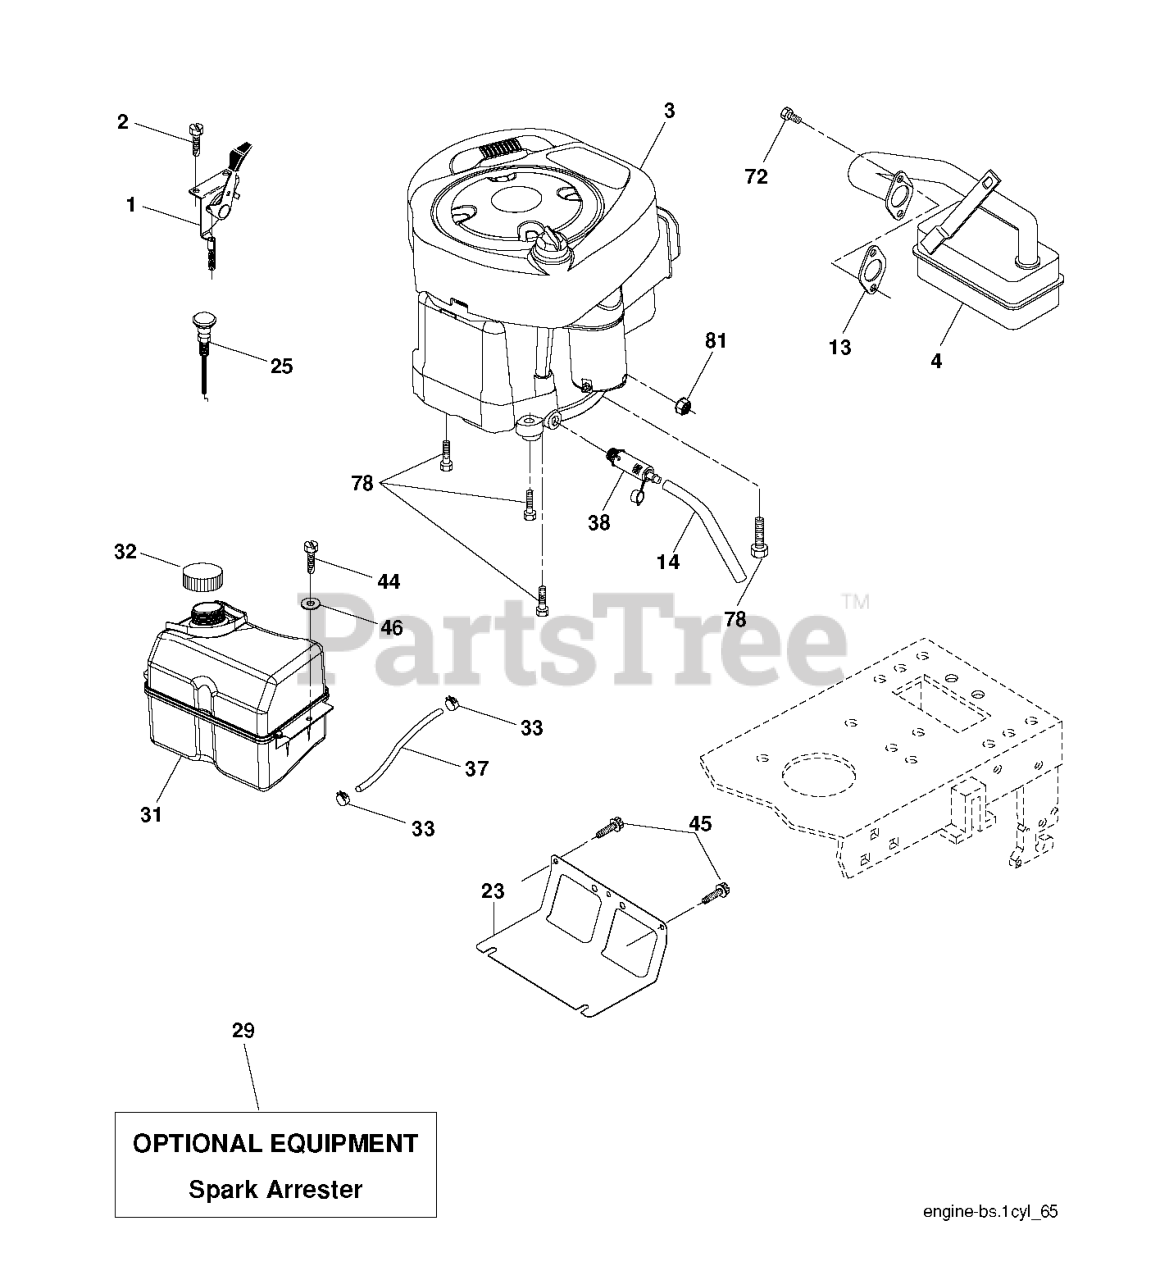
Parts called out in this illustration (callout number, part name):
1	CONTROL.THROTTLE/CHOKE.BLACK
2	SCREW
4	MUFFLER.B&S.MODEL.21.11HP.OHV
13	REPL BY 532 27 22-93
14	TUBE, DRAIN OIL ASM.
23	SHIELD.BROWNING.DBR.GUARD
25	KNOB.ERGO.EXTENDED.RED (1 2)
29	KIT.SPARK ARRESTOR 794945 B&S
31	TANK.FUEL.FRT.N/CAP.2.0GAL.DAP
32	FUEL CAP
33	HOSE CLAMP
37	LINE.FUEL.20
38	PLUG DRAIN OIL EASY
44	SCREW HEXWSHR 1/4-20X3/4
45	SCREW, 3/8-16X3/4
72	SCREW.SOCKET HD.5/16-1
78	SCREW.3/8-16
81	NUT
